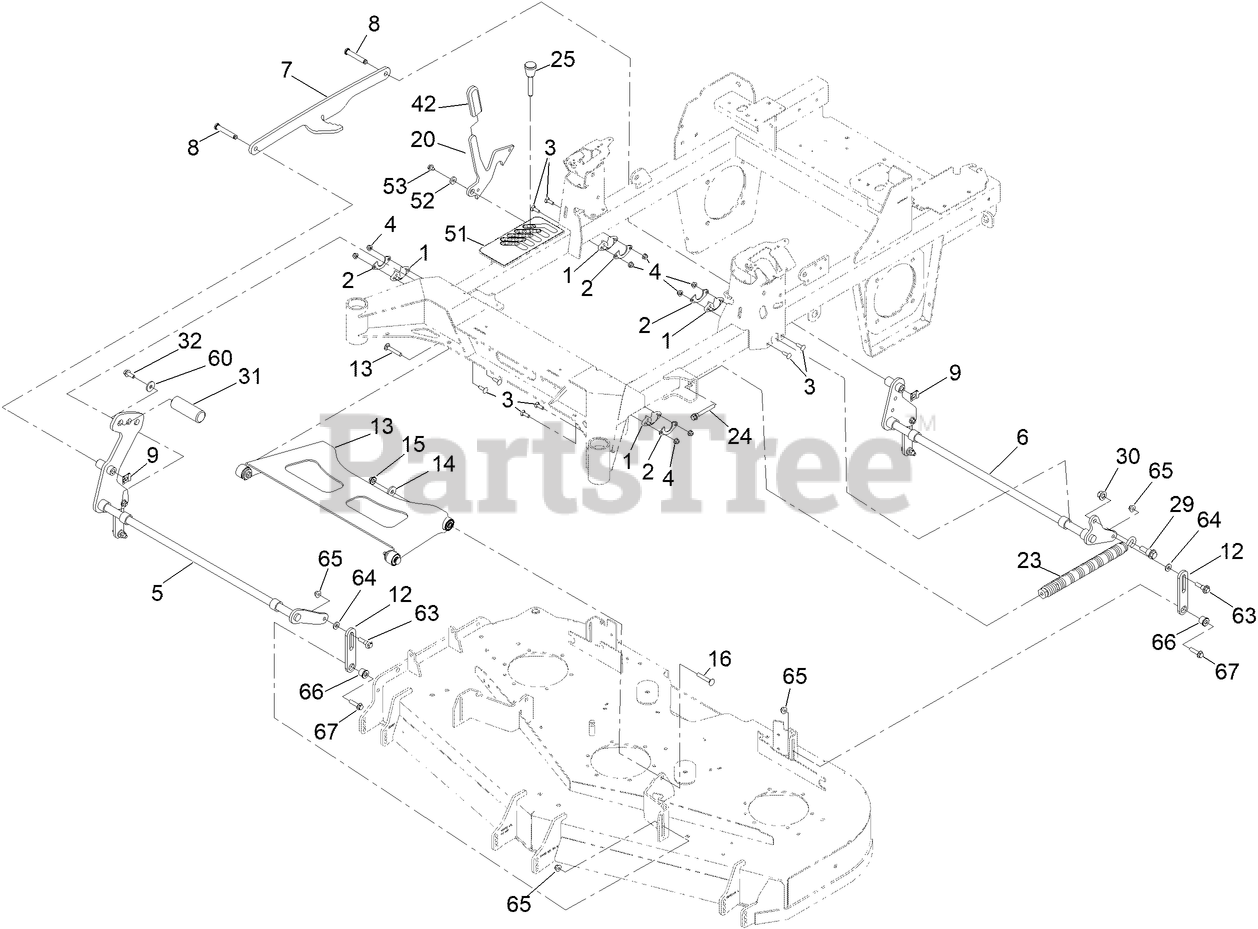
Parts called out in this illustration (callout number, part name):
1	BEARING-FLANGE
2	GUSSET-LIFT, DECK
3	SCREW-CARR
4	NUT-HF, NI
5	DECK LIFT SHAFT ASM, FRT [BLACK
6	DECK LIFT SHAFT ASM [BLACK]
7	LINK-LIFT
8	PIN-CLEVIS
9	CLIP-PIN
12	LINK-LIFT, DECK
13	ASM-DECK STRUT W/ BUSHINGS
14	WASHER
15	NUT-FLANGE, NI
16	SCREW-CARR
20	PLATE-TRANSPORT LOCK
23	SPRING-EXTENSION
24	BOLT-SHOULDER
25	PIN-HOC
29	SCREW-SHOULDER, HHF
30	NUT-LOCK
31	PEDAL-FOOT LIFT
32	SCREW-HHF
42	GRIP-LEVER
51	DECAL-HOC
52	SPACER
53	SCREW
60	WASHER
63	BOLT-SHOULDER
64	SPACER
65	NUT-HF, NI
66	BUSHING-DECK LIFT
67	SCREW-HHF
